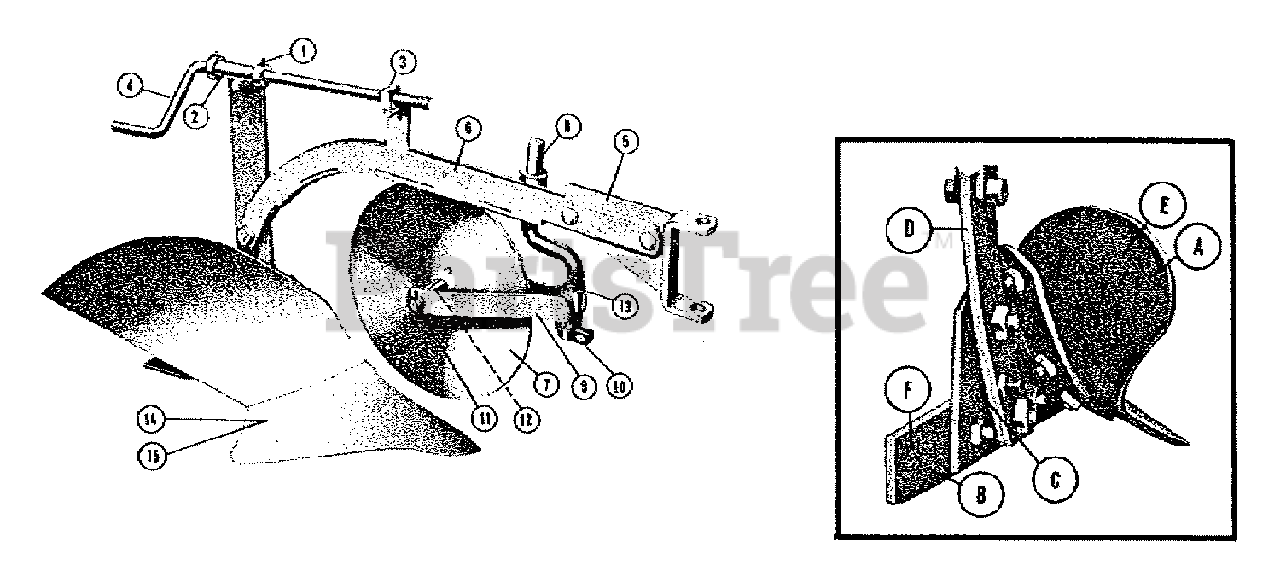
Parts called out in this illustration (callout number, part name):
1	SET COLLAR
2	DEPTH SCREW BEARING ASSEMBLY
3	DEPTH SCREW ADJUSTMENT NUT ASSEMBLY
4	DEPTH SCREW
5	BEAM END ASSEMBLY
6	PLOW BEAM ASSEMBLY
7	COULTER WITH BUSHINGS
8	STANDARD, Coulter
9	FORK ASSEMBLY
10	STOP ASSEMBLY
11	AXLE, Bolt
14	6 1/2" PLOW SHARE
15	8" PLOW SHARE
A	MOLDBOARD - 6 1/2" Plow
B	MOLDBOARD - 8" Plow
E	MOLDBOARD -8" Plow
F	LANDSIDE - 8" Plow
